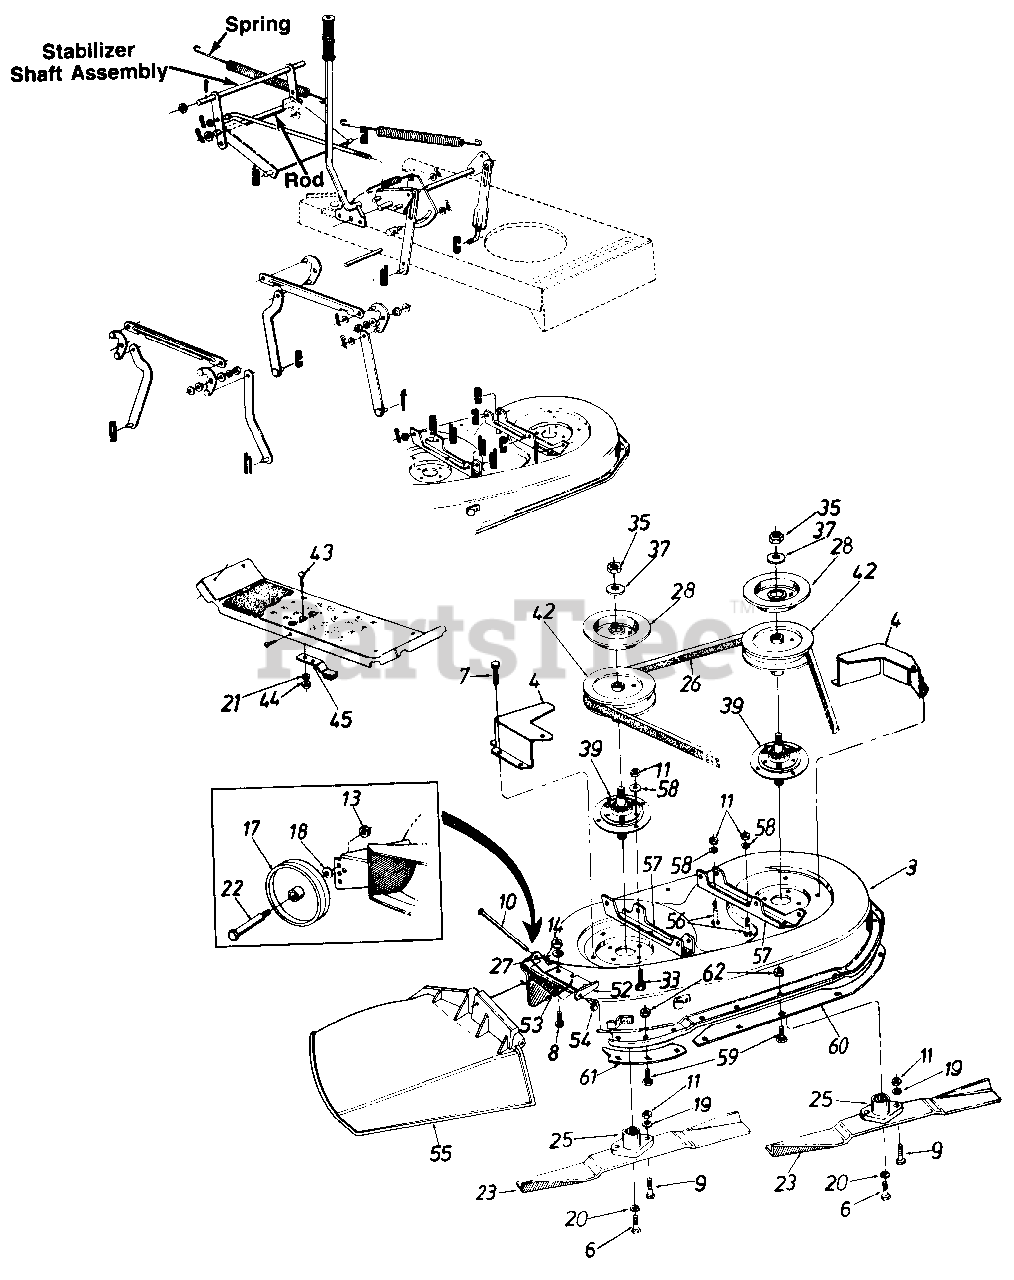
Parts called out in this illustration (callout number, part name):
3	42" Deck Ass'y.
6	Hex Bolt 3/8-24 x 1.0" Lg.
7	Hex Wash. Hd. TT-Tap Scr. 1/4-20 x .5" Lg.
8	Hex Bolt 1/4-20 x .62"
9	Hex Bolt Special 5/16-24 x 1
10	Hinge Pin
11	Hex Nut 5/16-24 Thd.
13	Hex Top L-Nut 3/8-16 Thd.
14	Hex Nut 1/4-20 Thd.
17	Deck Wheel 5"
18	Bell-Wash. .40" I.D. x .88" O.D.
19	L-Wash. 5/16" I.D.
20	L-Wash. 3/8" I.D. H.D.
21	L-Wash. 1/4" I.D.
22	Shld. Bolt .498" Dia. x 1.53"
23	High-Lift Blade
25	Blade Adapter
26	V-Belt
27	Bell-Wash. 1/4" I.D.
28	Brake Disc
33	Hex Bolt 5/16-24 x .75" Lg.
35	Hex Jam Nut 5/8-18 Thd.
37	L-Wash. 5/8" I.D.
39	Blade Spindle Ass'y. Comp.
42	5.5" Dia. Pulley
43	Carr. Bolt 1/4-20 x .62"
44	Hex Nut 1/4-20 Thd.
45	Blade Brake Ass'y.
52	Hinge Mtg. Brkt.
53	Torsion Spring
54	Push Nut
55	Chute Ass'y. Comp.
56	Hex Bolt 5/16-24 x .75" Lg.
59	Carr. Bolt 1/4-20 x .5" Lg.
60	Deck Skirt Ext. Long
62	Hex Sems Nut 1/4-20 Thd.
